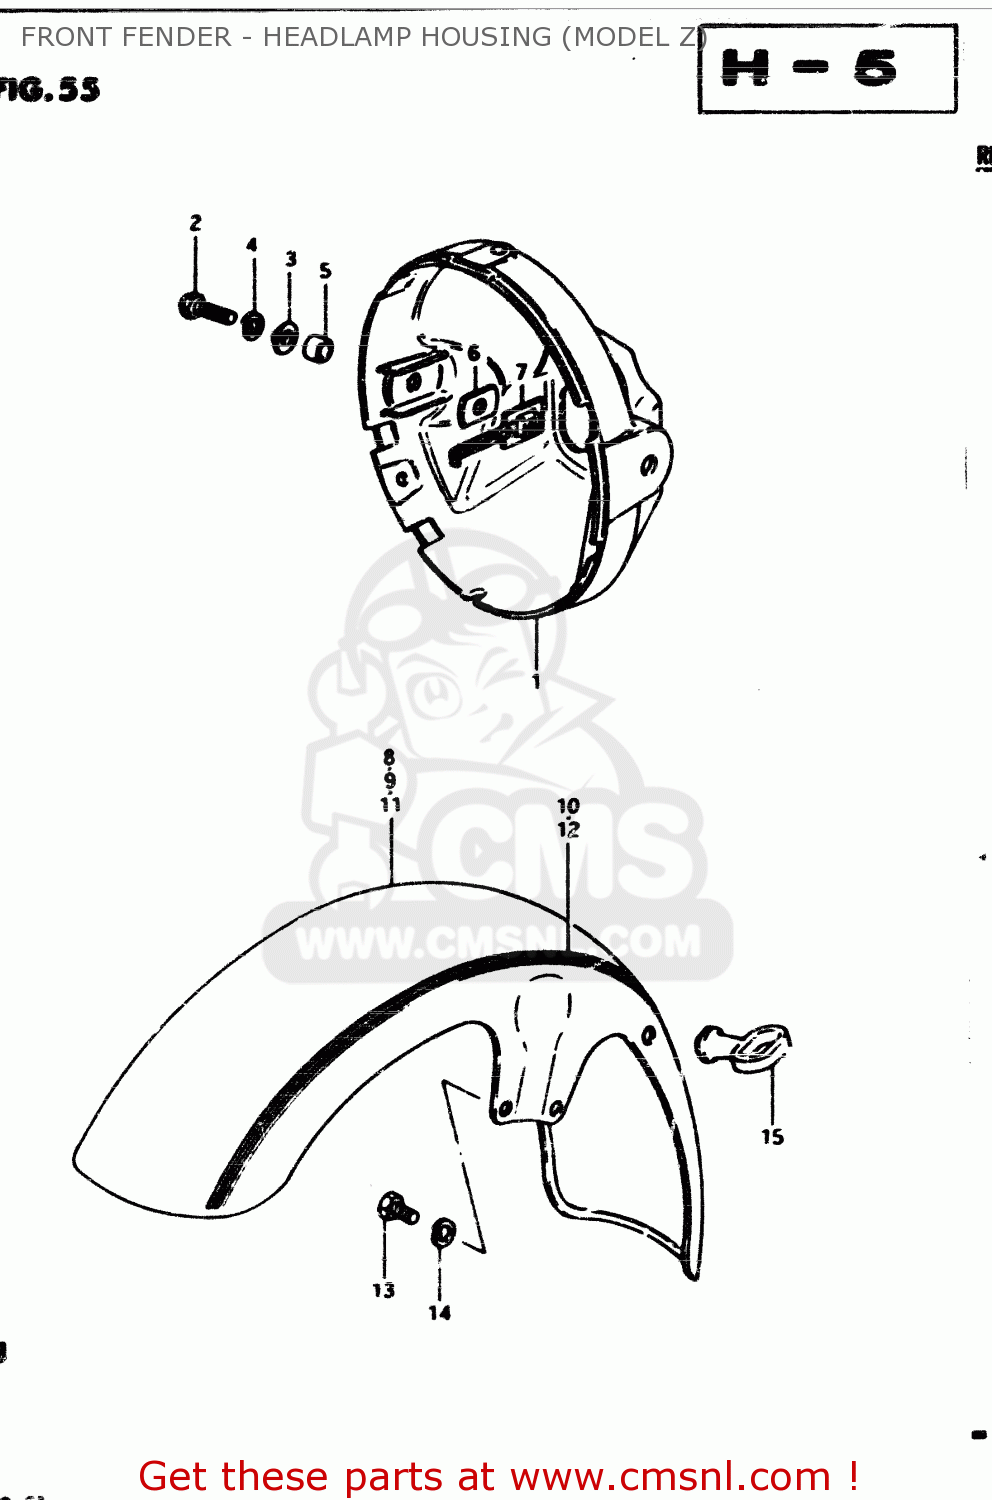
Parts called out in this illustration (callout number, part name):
1	HOUSING,HEADLAMP
2	BOLT
3	WASHER
4	LOCK WASHER
5	SPACER (8.8X12X7)
6	CUSHION
7	PLATE,HEADLAMP HOUSING
8	FENDER, FRONT
9	FENDER, FRONT
10	TAPE
11	FENDER, FRONT
12	TAPE
13	BOLT
14	LOCK WASHER
15	GUIDE,CABLE
